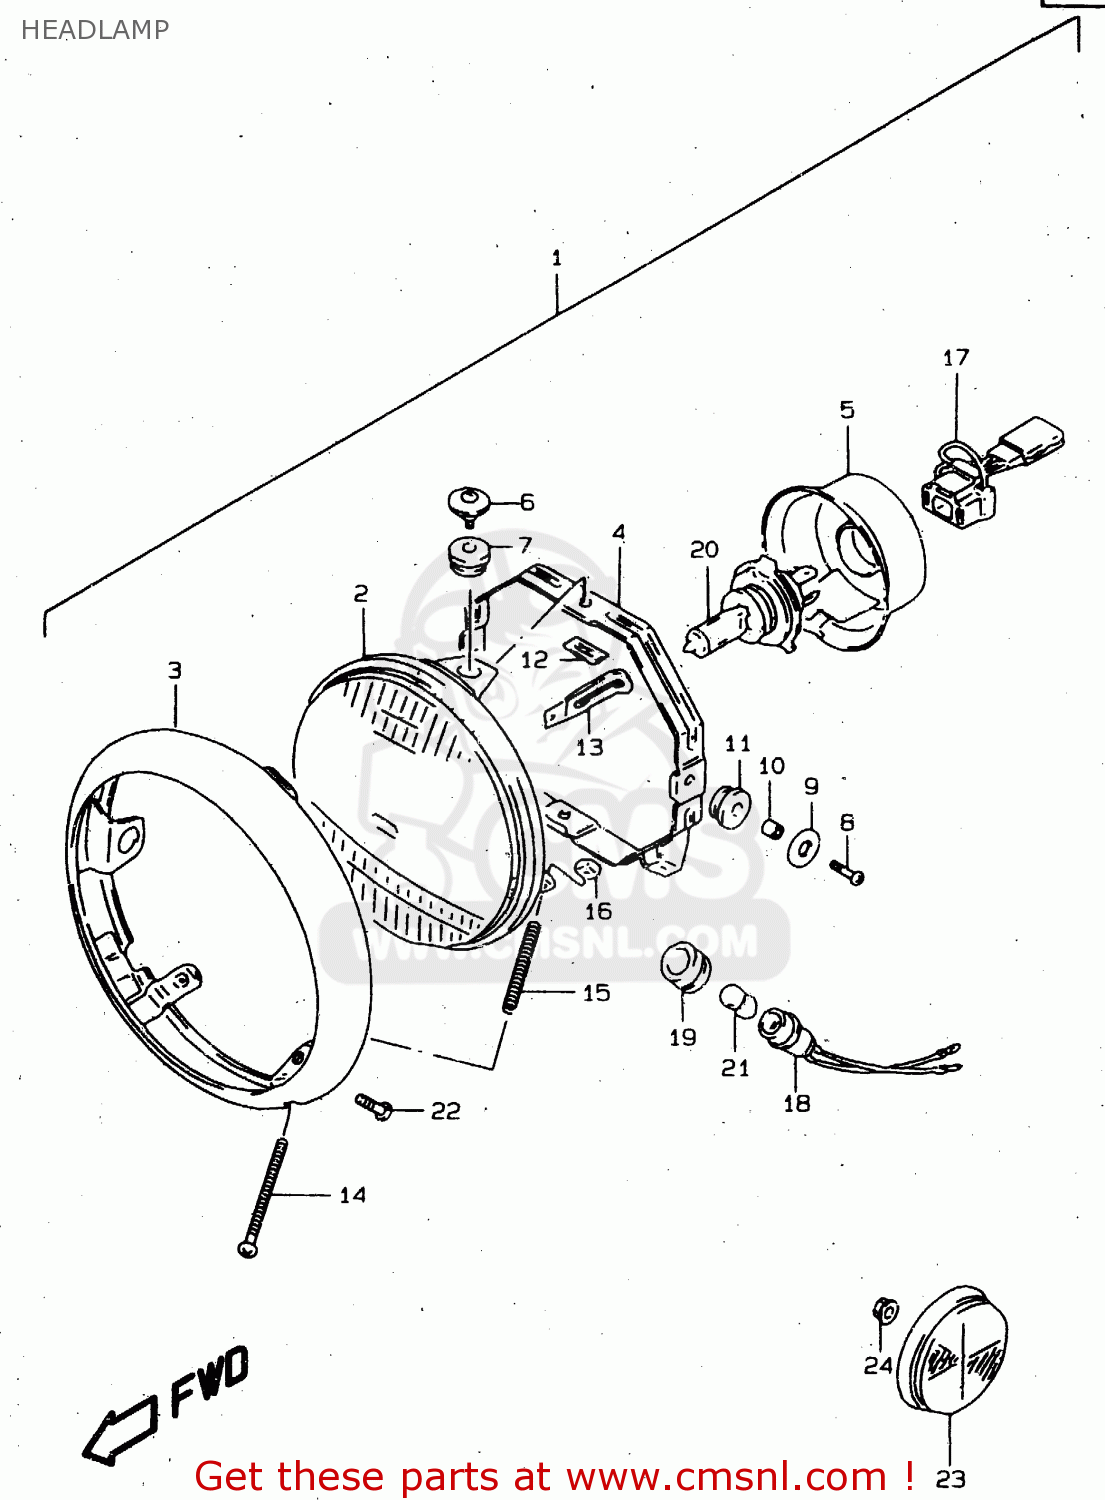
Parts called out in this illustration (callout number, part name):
1	HEADLAMP ASSY
2	UNIT
3	RIM
4	RING,MOUNTING
5	COVER,SOCKET
6	SCREW,MOUNTING
7	CUSHION
8	SCREW
9	WASHER(5.5X18X1)
10	SPACER
11	CUSHION
12	NUT
13	CLAMP(L:65)
14	SCREW,ADJUSTING(4X50)
15	SPRING
16	NUT
17	SOCKET
18	SOCKET
19	JOINT,RUBBER
20	BULB(12V60/55W,H4)
21	BULB(12V4W)
22	SCREW
23	REFLECTOR,REFLEX FR
24	NUT
